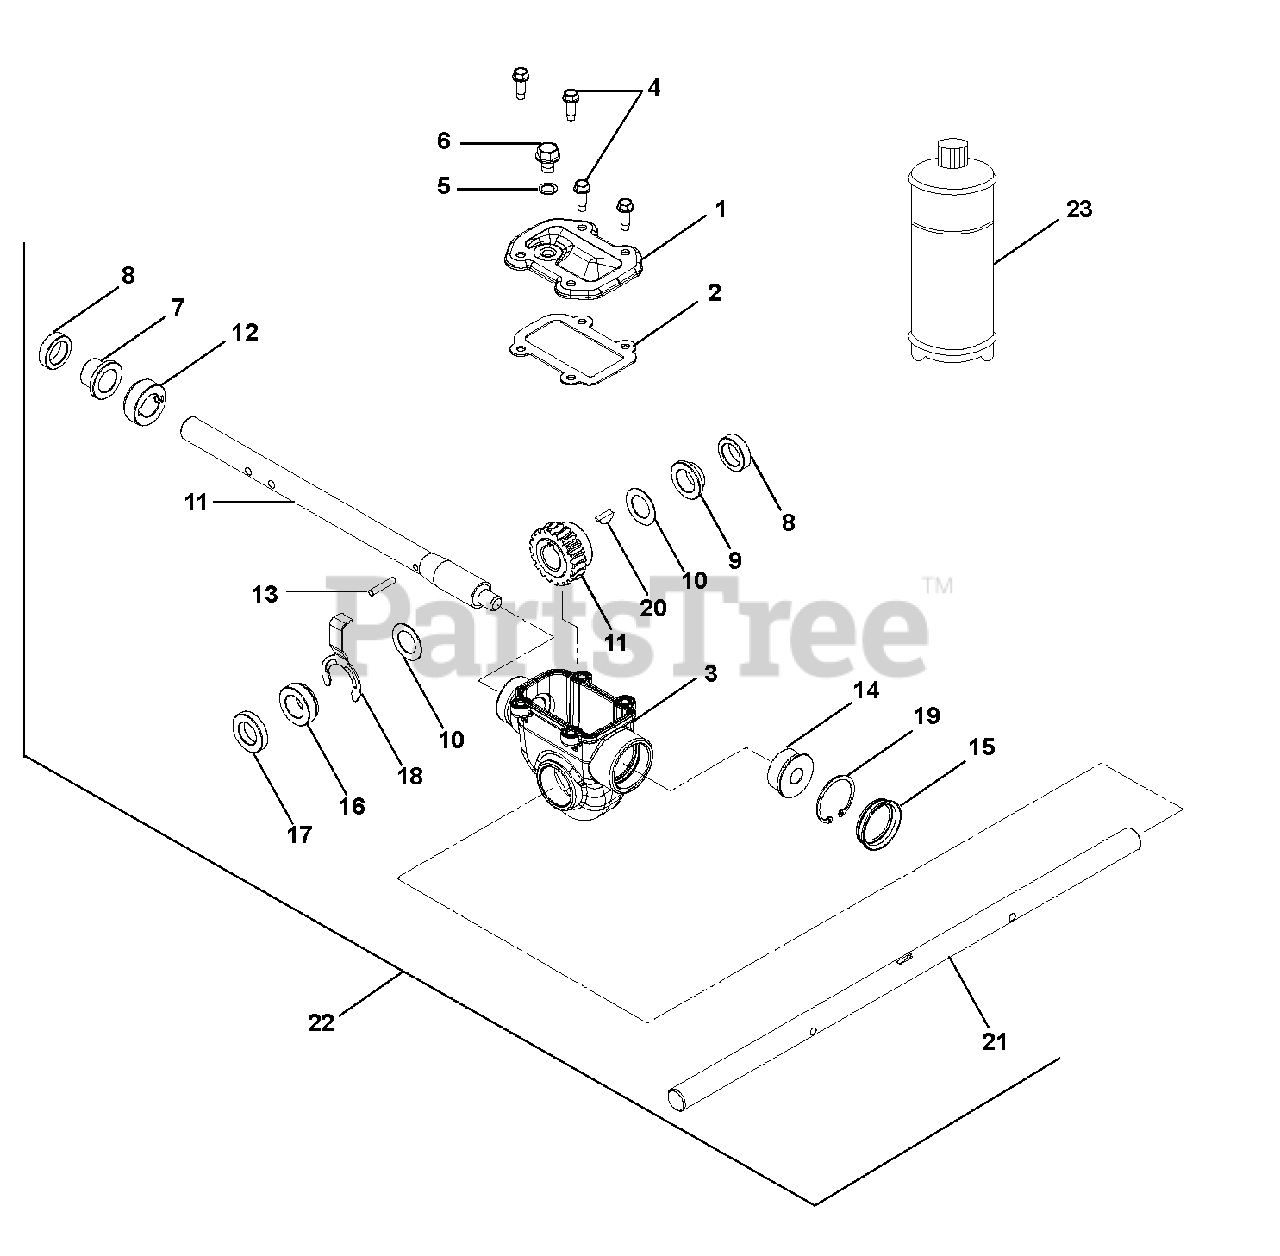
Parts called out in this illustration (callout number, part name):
1	COVER, TOP - COMPACT
2	GASKET, TOP - COMPACT GEARCASE
3	GEARCASE, COMPACT ALUMINUM
4	SCR-TAP .25-20X.75 HWH TR YWZ
5	WSHR-BND-SEAL .38X.75X.11 GALV
6	@SCR-TAP .38-16X.50 HWH TR YWZ
7	BSHG-FLG .755X.878X.75X1.25
8	SEAL-OIL .748X1.125X.312 TBC29
9	BSHG-FLG .755X.878X.424X1.25
10	WSHR-FL-STL .760X1.225X.032 YZ
11	SHAFT AND WORM GEAR ASSEMBLY
12	THRUST COLLAR, .75" ID SLIPFIT
13	PIN-STR .188X1.00 6150
14	BSHG-FLG .503X1.303X.62X1.465
15	COVER, GEAR CASE 1.50"
16	BSHG-FLG COMPACT, RIGHT
17	SEAL-OIL .748X1.300X.250 TBC29
18	BUSHING RETAINER, COMPACT
19	RG-RTNG-INT 1.500X.050
20	KEY-WDRF .19X.63 HRD #61
21	SHAFT, RAKE - 20" (.750 DIA)
22	GEAR CASE, 20" ALUM SM TOP-LD
23	ARIENS L3 LUBE, 8 OZ BOTTLE
